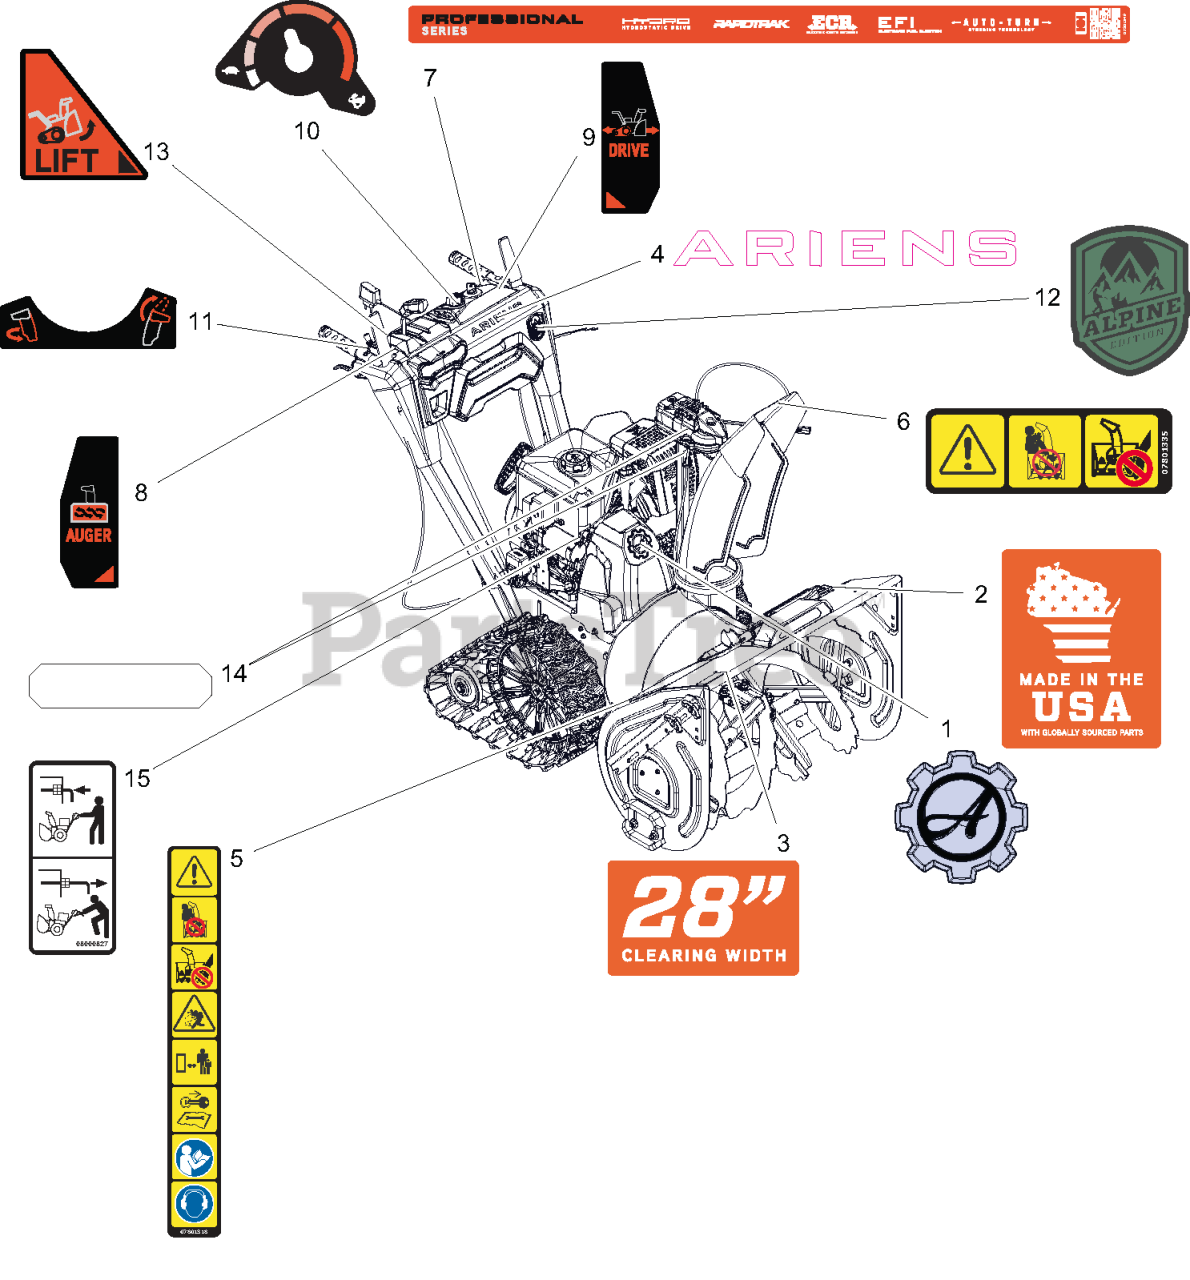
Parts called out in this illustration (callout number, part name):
1	DECAL- ARIENS GEAR BADGE
2	DECAL- MADE IN USA
3	DECAL- CLEARING - 28
4	DECAL- ARIENS - 7.46"
5	DECAL- SAFETY - DANGER
6	DECAL- DANGER
7	DECAL- DASH - PRO TRK EFI
8	DECAL- CONTROL - AUGER
9	DECAL- CONTROL - DRIVE TRACK
10	DECAL- CONTROL - EFI SPEED
11	DECAL- CONTORL - ECR
12	DECAL- BADGE - ALPINE
13	DECAL- CONTROL - TRACK LIFT
14	DECAL,REFLECTIVE,GEAR COVER
15	DECAL, BYPASS
